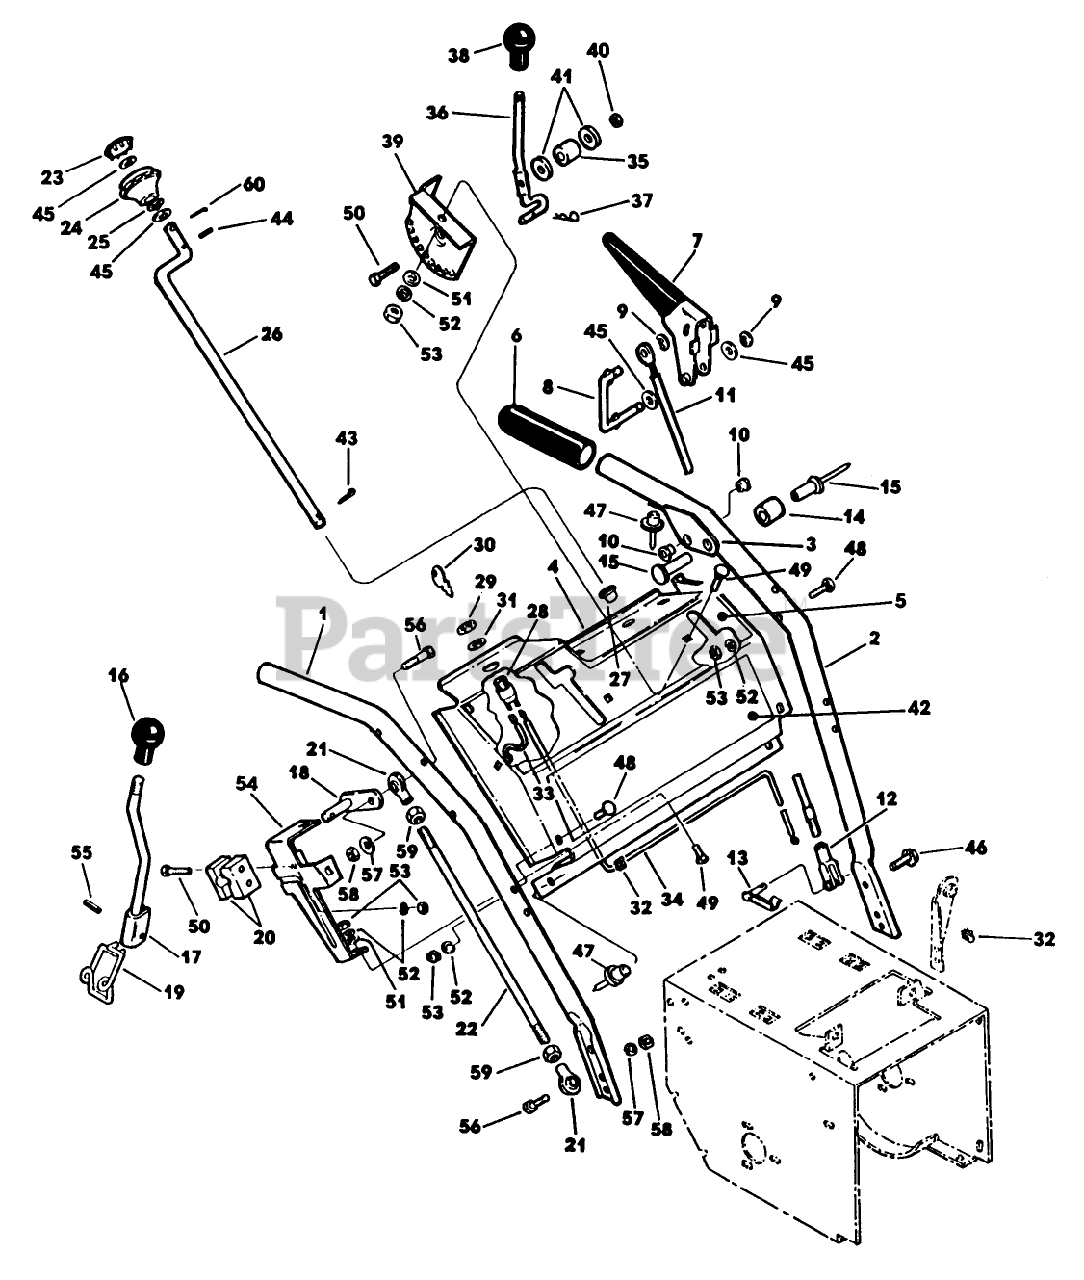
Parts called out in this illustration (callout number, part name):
1	HANDLE-R.H.
6	GRIP
8	ROD CONTROL
11	CABLE ASM
12	YOKE-ADJUSTABLE
13	SPRING CLEVIS PIN
20	SHIFT LEVER BLOCK
23	PLUG BUTTON-KNOB
24	KNOB
32	CLIP
37	PIN-HAIR
40	NUT-LOCK, CONE
43	PIN-COTTER
45	WASHER
47	Pop Rivet
53	NUT
57	WASHER
58	NUT
59	NUT-HEX
